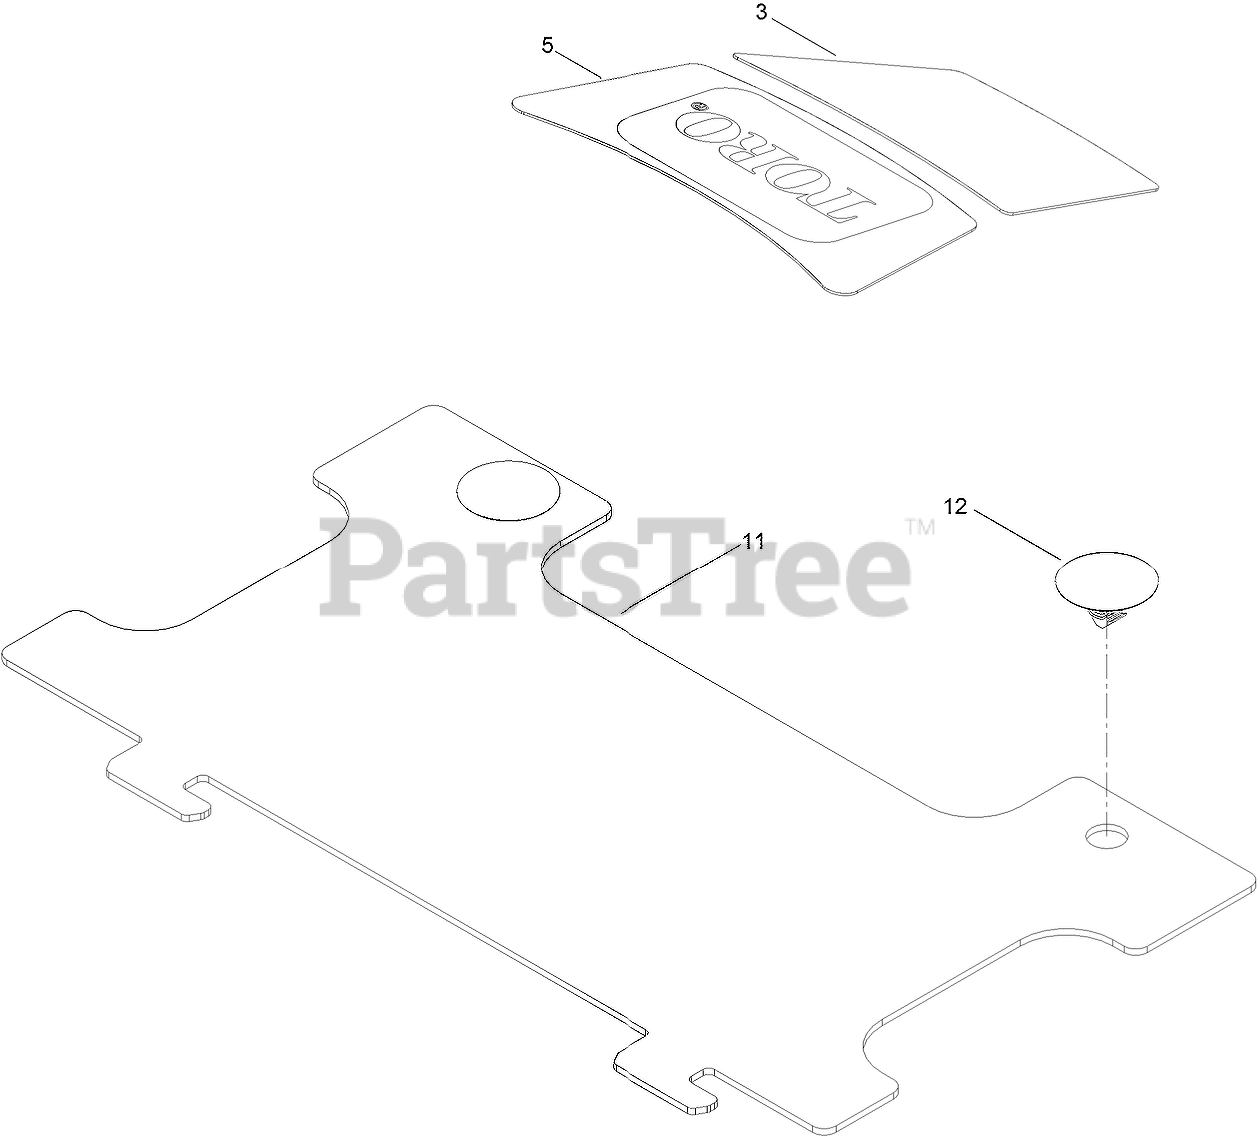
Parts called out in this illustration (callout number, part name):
3	DECAL-DISPLACEMENT, ENGINE
5	DECAL-ENGINE
11	SHIELD
12	RIVET-PLASTIC
